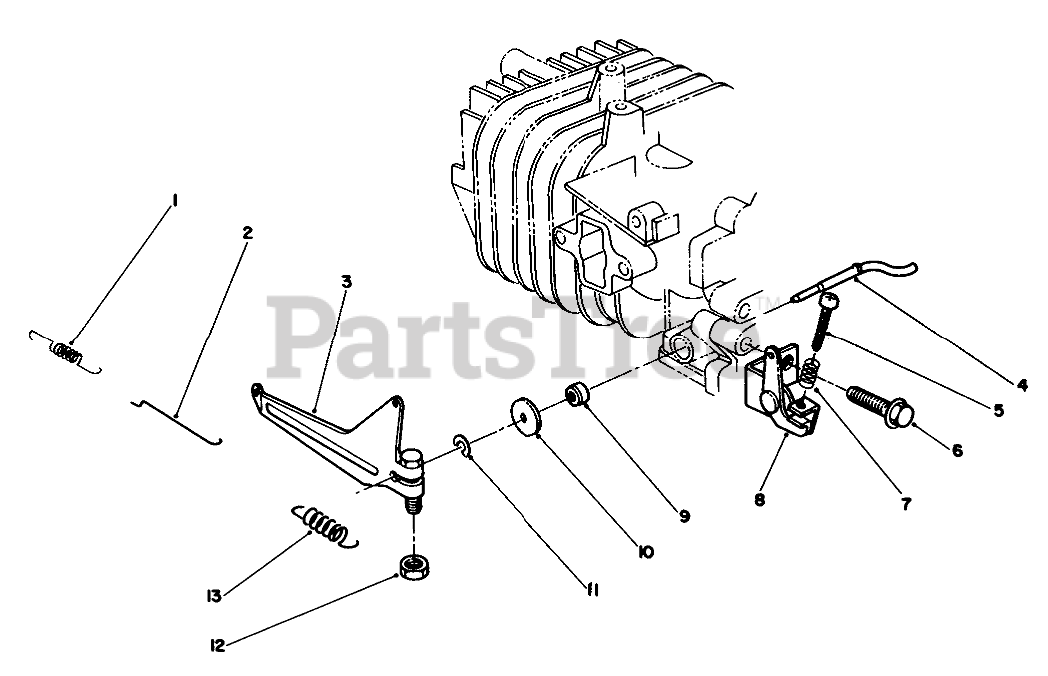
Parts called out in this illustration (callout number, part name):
1	CARB SPRING
2	CARB ROD
3	GOV ARM
4	SHAFT
5	SCREW
7	SPRING
8	GOV SPR BRKT
9	SEAL-OIL
10	WASHER
11	E-RING
13	GOV SPRING
